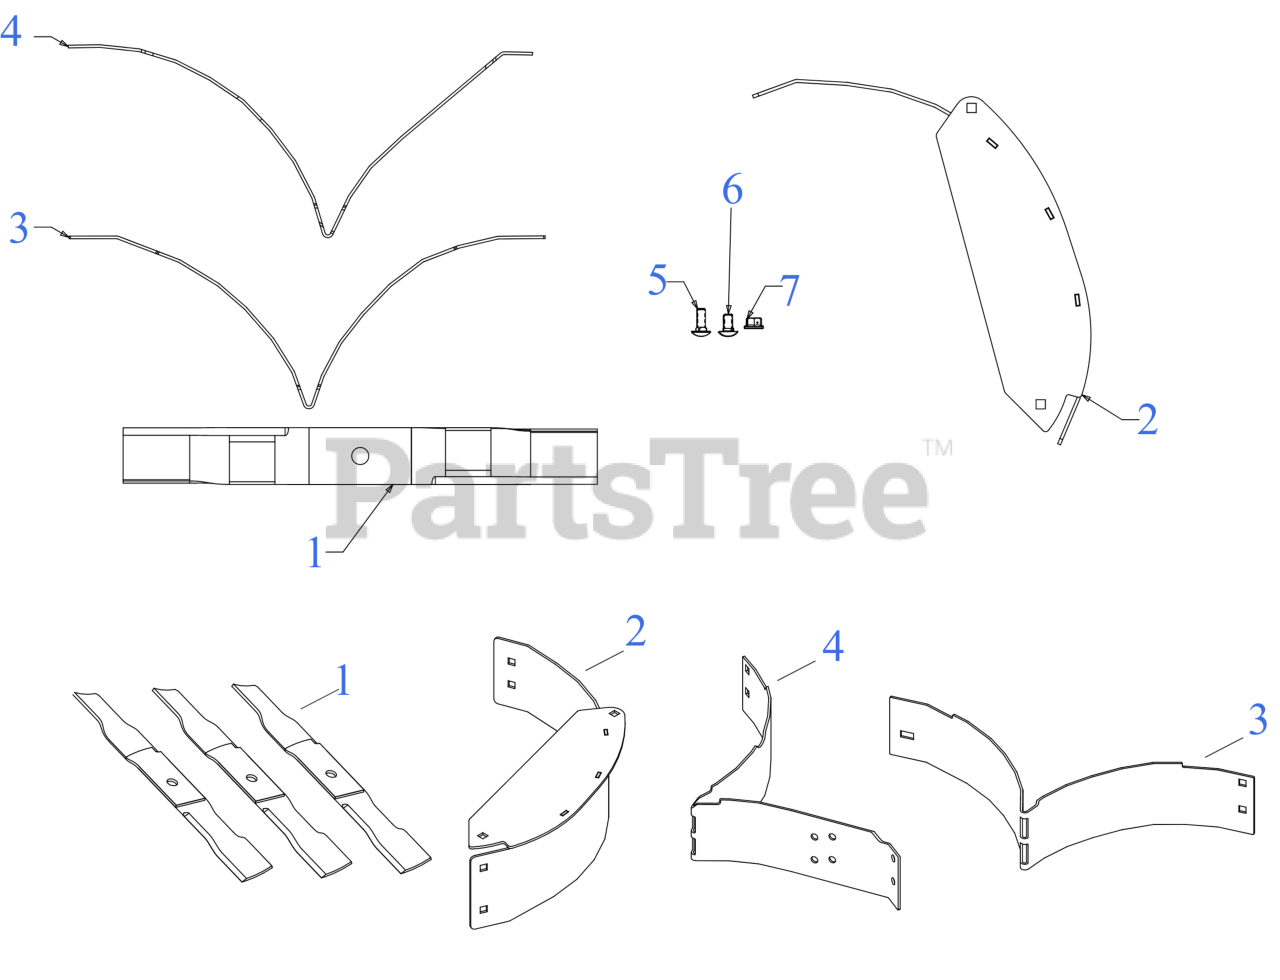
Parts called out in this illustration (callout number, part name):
1	BLADE-21"MULCH 60"
2	60" DISCHARGE MULCH BAFFLE
4	60" MULCH BAFFLE (CENTER)
5	CARRIAGE BOLT 3/8-16 x 1.00 GR5
6	CARRIAGE BOLT 3/8-16 x .75
7	NUT-CTRLCK FLG HEX
